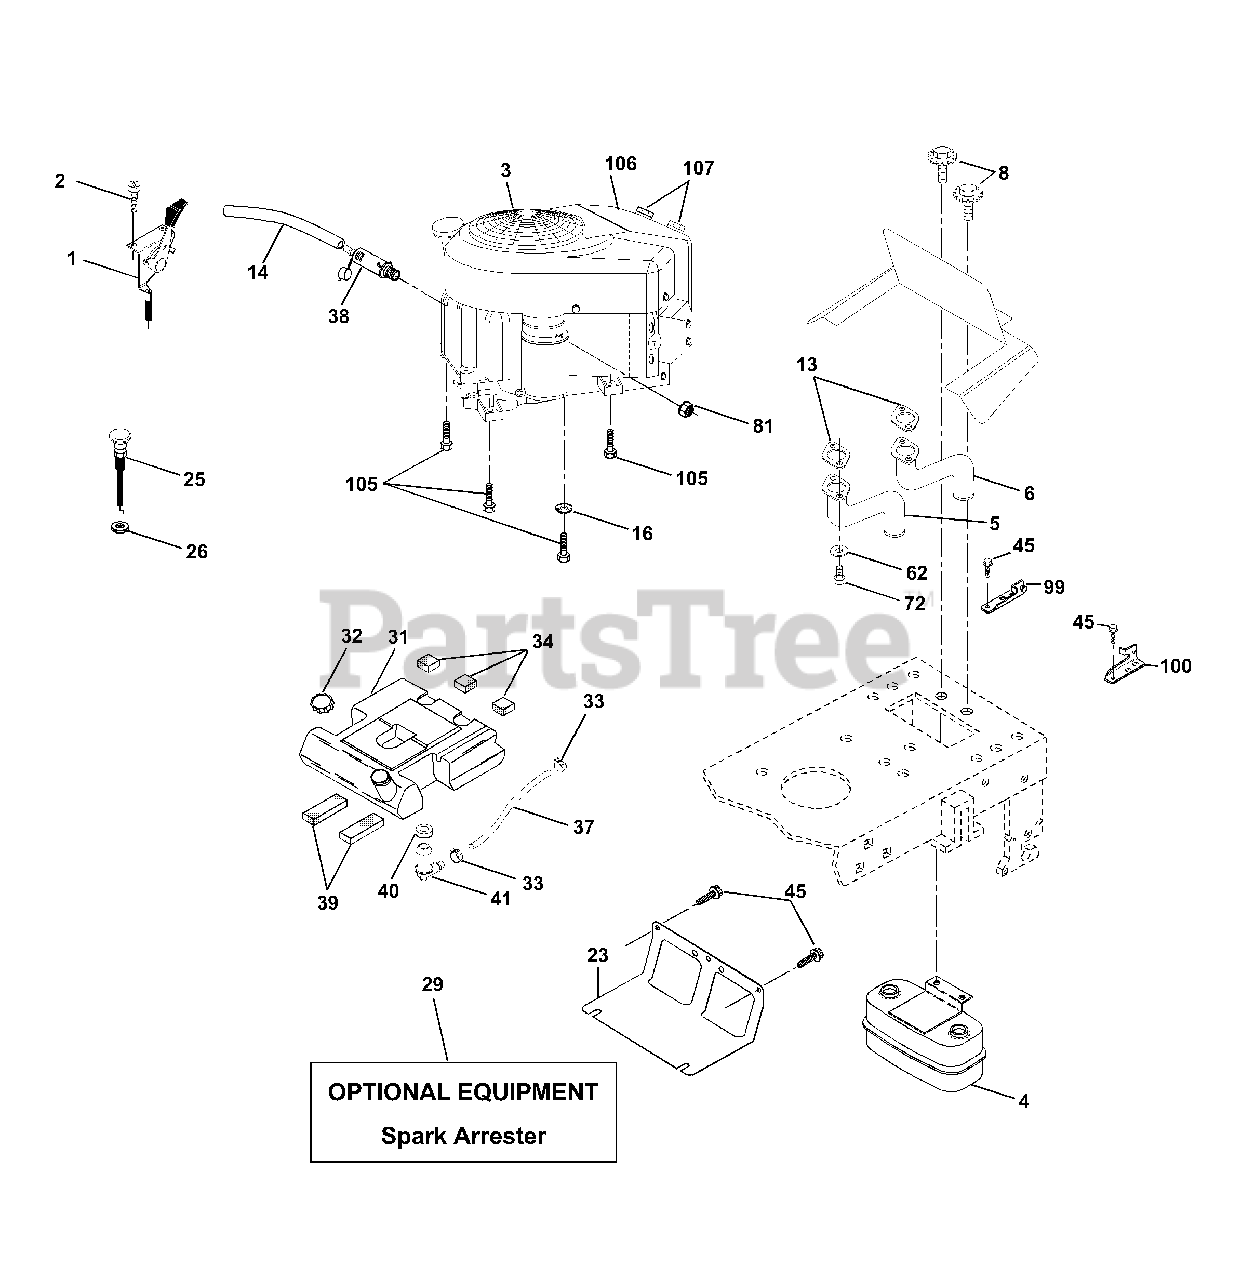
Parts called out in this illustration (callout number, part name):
1	Control, Throttle
2	Screw, Hex Head, Thread Cutting 1/4-20 x 5/8
4	Muffler
5	Tube, Exhaust, LH
6	Tube, Exhaust, RH
7	Clip Insulated
8	Bolt 5/16-18 UNC x 3/4 w/Sems
10	Shield, Browning
13	Muffler Gasket
14	Tube Drain Oil Easy
16	Washer, Lock, External Tooth 3/8
23	Shield, Browning / Debris Guard
25	Choke Control
26	Nut, Keps 3/8-24 UNF
29	Kit, Spark Arrestor
31	Tank Fuel 3 50 Rear
32	Cap Fuel Gauge
33	Clamp, Hose
34	Pad, Spacer
37	Line, Fuel
38	Plug Drain Oil Easy
39	Pad, Idler
40	Bushing
41	Stem, Fuel Tank
45	Screw Hex wsh Thdrol 3/8-16 x 3/4
62	Washer Lock 5/16
72	Screw Hex Hd Cap 5/16-18 x 3/4
81	Nut Keps Hex 1/4-20 Unc
99	Bracket Asm Pivot Lh Raised
100	Bracket Asm Pivot Rh Raised
105	Screw 3/8-16 x 1
106	Control Cover
